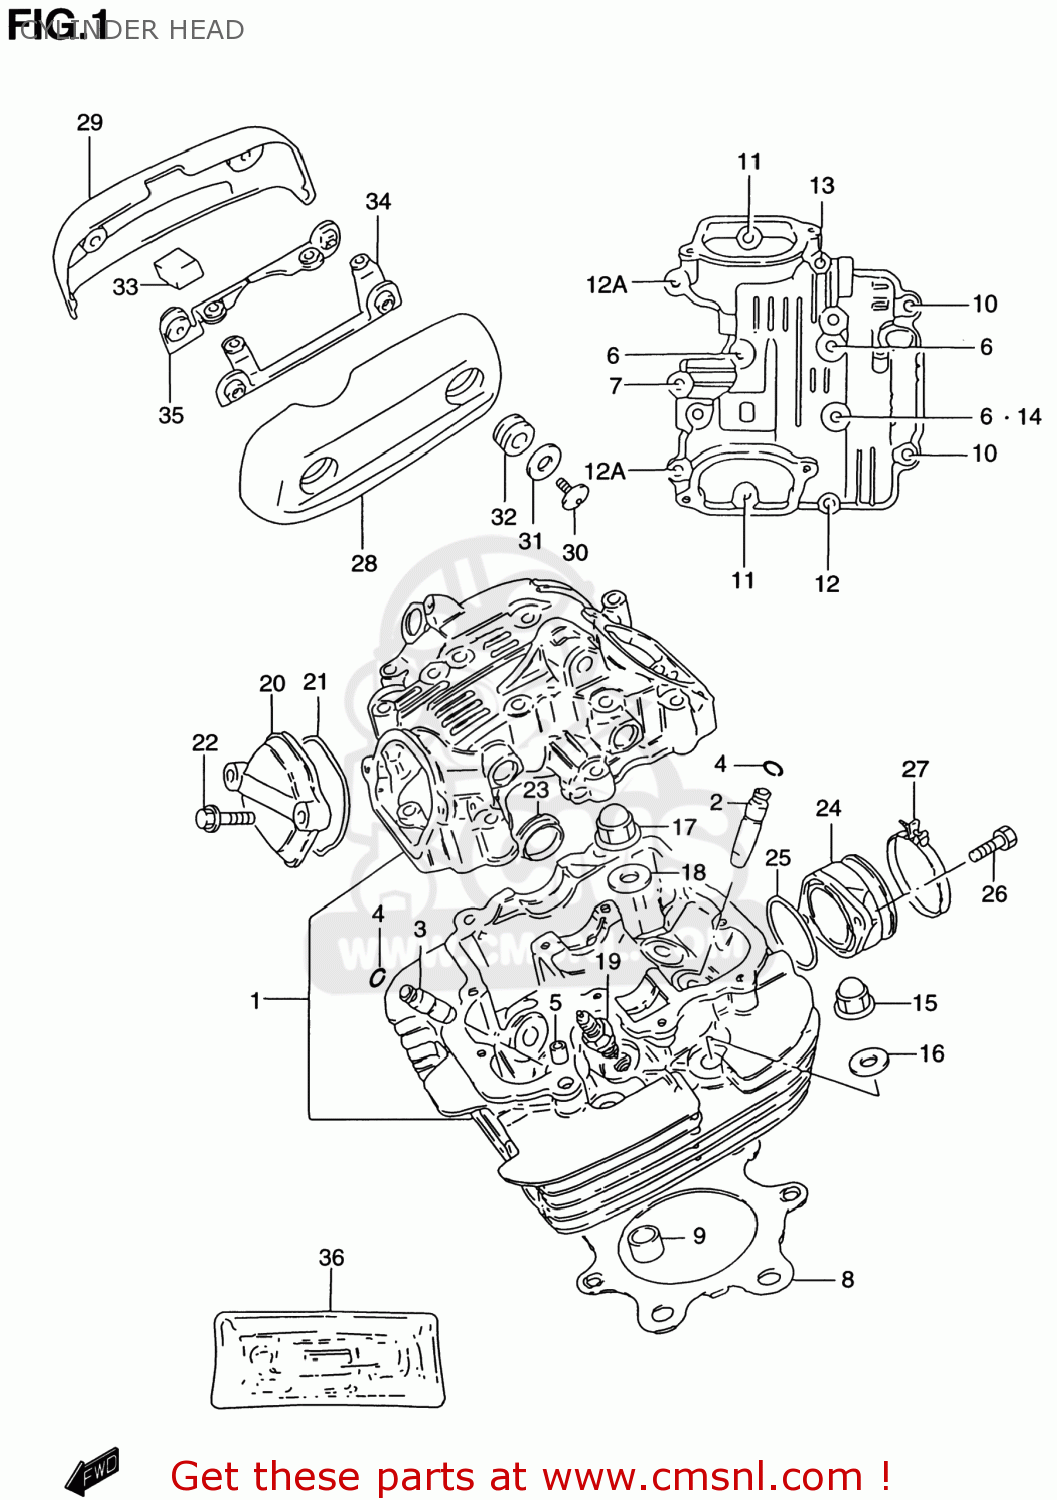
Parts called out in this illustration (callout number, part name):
1	HEAD ASSEMBLY,CYLINDER
2	GUIDE,INTAKE VALVE
3	GUIDE,VALVE
4	RING,SNAP
5	PIN(6.2X8X11)
6	BOLT
7	BOLT
8	GASKET,CYLINDER HEAD (NAS)
9	PIN
10	BOLT(6X120)
11	BOLT
12	BOLT
12A	BOLT
13	BOLT
14	GASKET(5.8X13X1.2) (NAS)
15	NUT
16	WASHER (10.5X22X2.3)
17	NUT
18	GASKET(10.5X22X2) (NAS)
19	PLUG,SPARK(DR8EA)
20	CAP,INSPECTION
21	O RING(D:2.4,ID:23)
22	BOLT
23	PLUG(OD:30)
24	PIPE,INTAKE
25	O RING(D:2.4,ID:39.7)
26	SCREW ,6X16
27	CLAMP
28	CAP,CYLINDER HEAD COVER,L
29	CAP,CYLINDER HEAD COVER,R
30	BOLT
31	WASHER(6.5X24X1.6)
32	CUSHION
33	DAMPER,HEAD CAP,R
34	BRACKET COMP,HEAD CAP
35	BRACKET COMP,HEAD CAP
36	GASKET SET (NAS)
